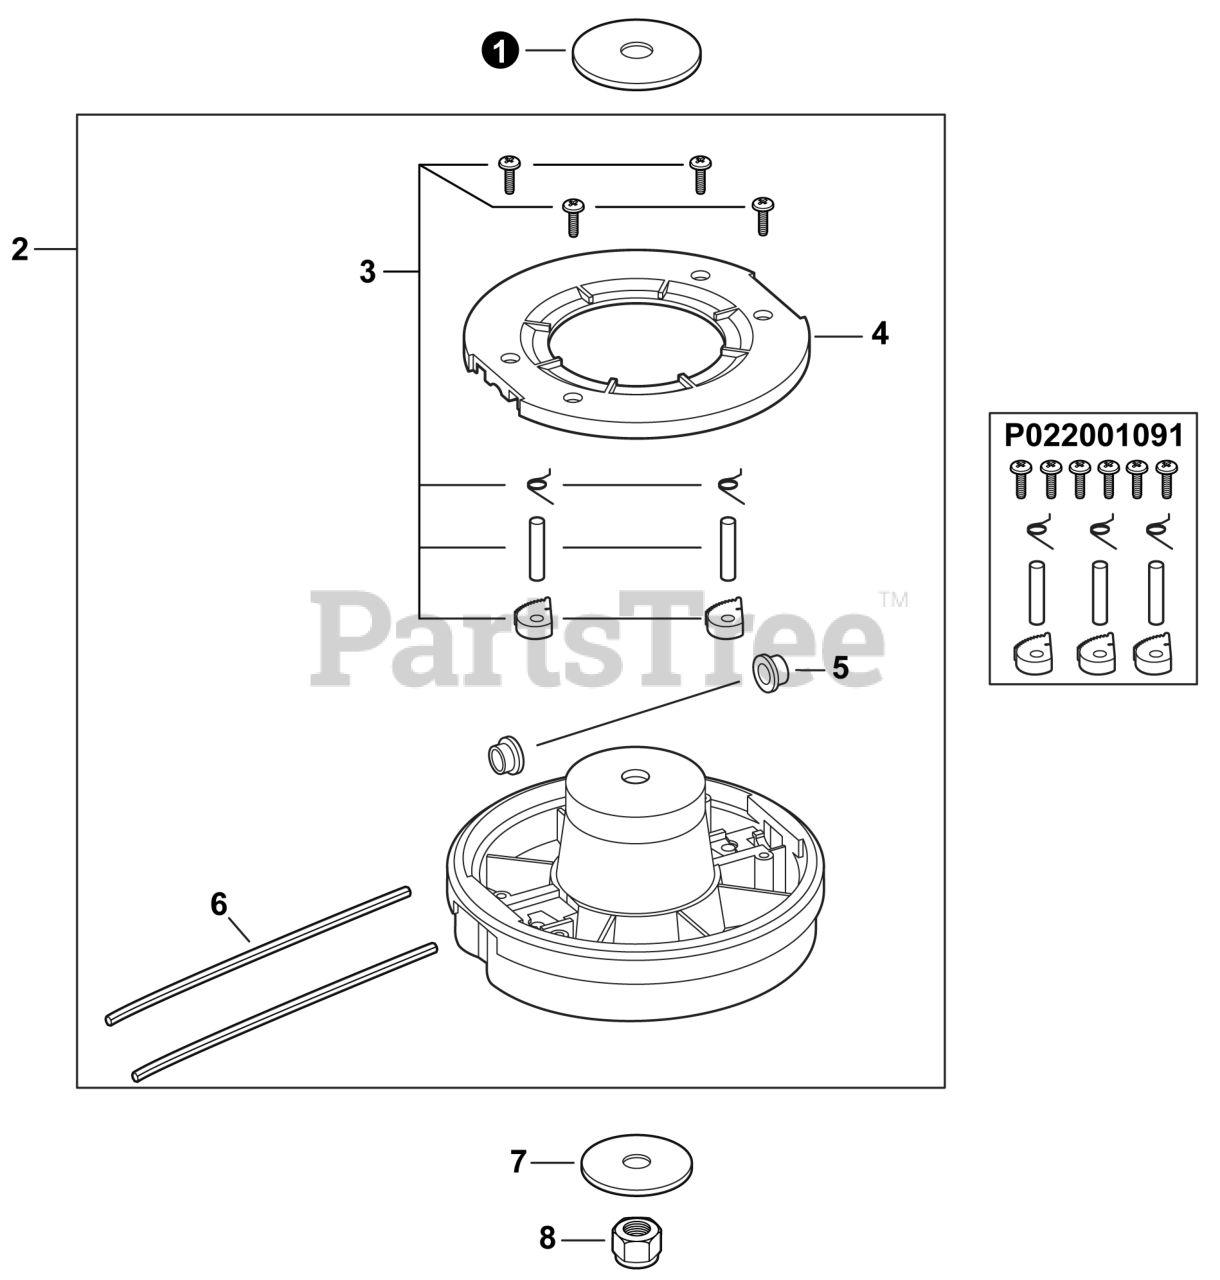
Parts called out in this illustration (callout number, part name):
1	WASHER 10
2	TRIMMER HEAD, RAPID-LOADERT- 2 LINE
3	PAWL KIT
4	COVER, TOP
5	EYELET (PACKAGE OF 3)
6	LINE, TRIMMER - 0.080 DIA. (PKG. OF 20)
7	WASHER 10
8	NUT, LOCK
